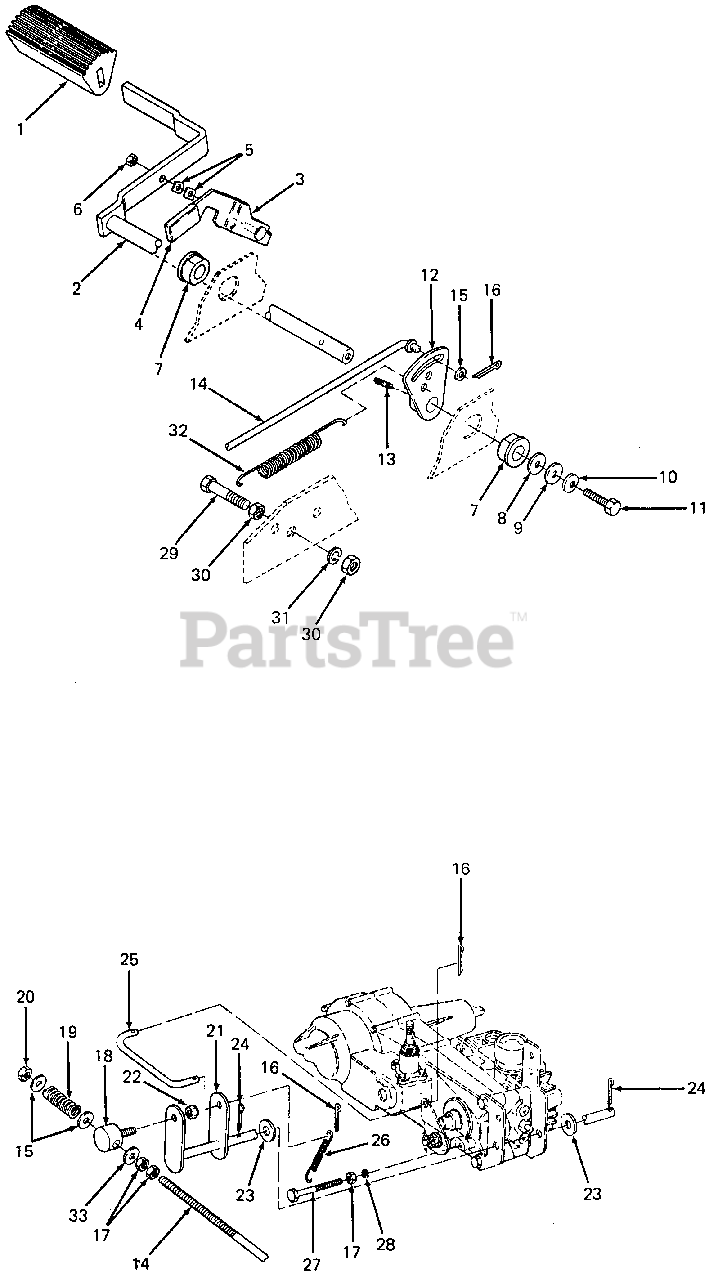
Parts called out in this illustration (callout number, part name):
1	Pad, Foot
5	Washer, Wave
6	Nut, Hex Insert Lock, 1/4-20
7	Bearing, Flange
8	Washer, Flat, .635 X 1.12 X .090 Thk
9	Washer, Flat, .26 X .93 X .120 Thk
10	Washer, Bell, .265 X .75 X .062 Thk
11	Screw, Hex Cap, 1/4-20 X .75 Lg GR5
12	Cam, Brake
13	Pin, Spiral Spring, 3/16 Dia X 1.5 Lg
14	Rod, Brake
15	Washer, Flat, .281 X .73 X .063 Thk
16	Pin, Cotter, 3/32 X .75 Lg
17	Nut, Hex Jam, 1/4-20
19	Spring, Compression, .58 OD X 2.00 Lg
20	Nut, Hex Patch Lock, 1/4-20
21	Shaft, Brake
22	Nut, Hex Insert Lock, 5/16-18
23	Washer, Flat, .510 X 1.0 X .060 Thk
24	Pin, Cotter, 1/8 Dia X 1.0 Lg
25	Link, Brake
26	Spring, Extension
27	Screw, Hex Patch, 1/4-20 X 1.5 Lg GR5
28	Washer, Lock, 1/4
29	Screw, Hex Cap, 3/8-16 X 3.0 Lg
30	Nut, Hex, 3/8-16 GR5
31	Washer, Lock, 3/8
32	Spring, Extension, .50 OD X 3.97 Lg
33	Washer, Flat, .281 X .50 OD X .063 Thk
